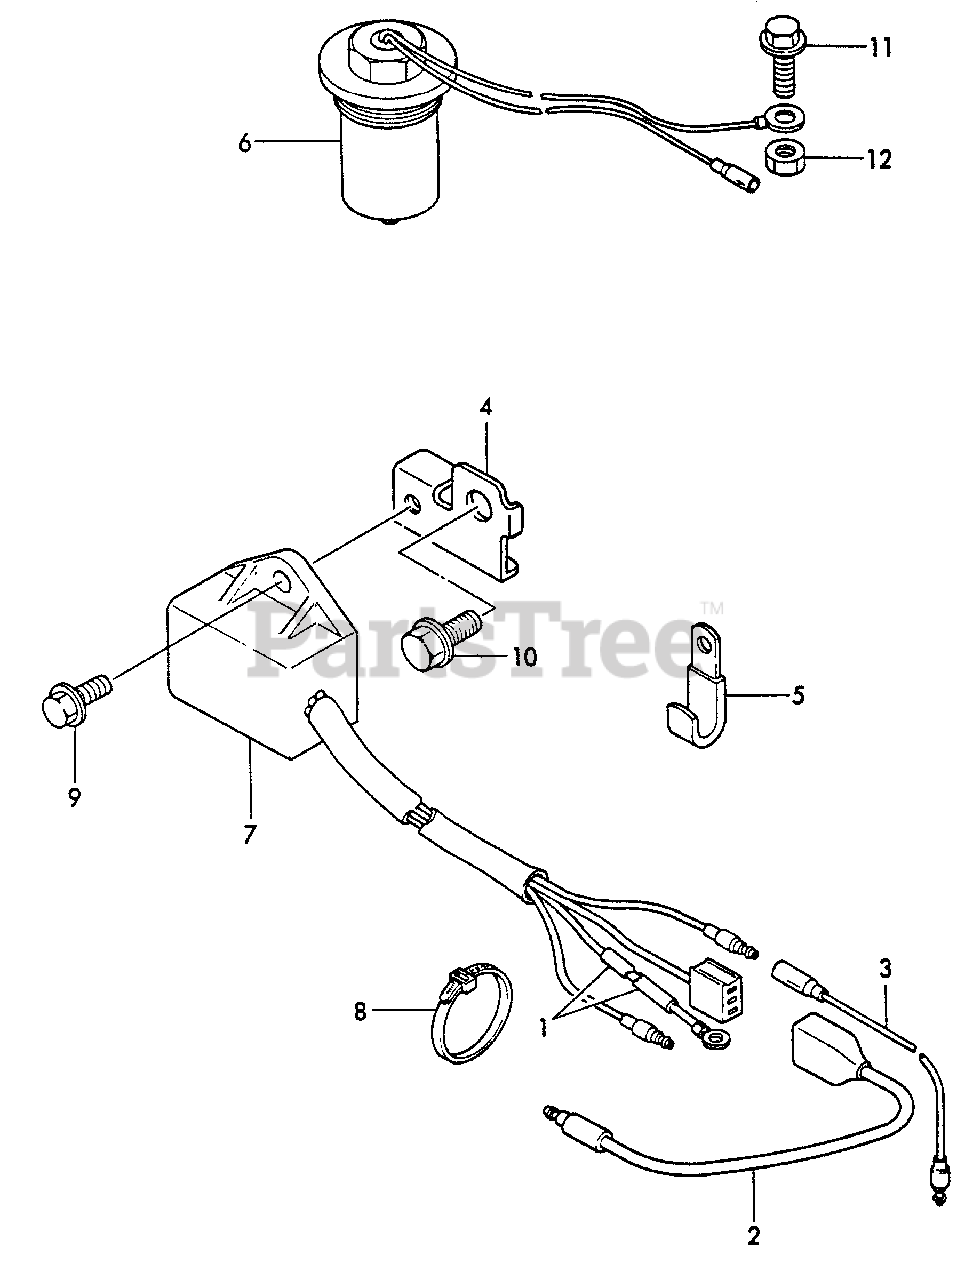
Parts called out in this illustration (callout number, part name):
1	TUBE, INSULATOR
2	WIRE
3	WIRE, SENSOR UNIT
4	STAY, SENSOR UNIT
5	CLAMP
6	SENSOR, OIL LEVEL
7	SENSOR UNIT, OIL
8	CLAMP
9	BOLT - 6×12 -- PLATED
10	BOLT - 8×14 -- PLATED
11	BOLT - 6×16 -- PLATED
12	LOCKNUT - 6 -- PLATED
